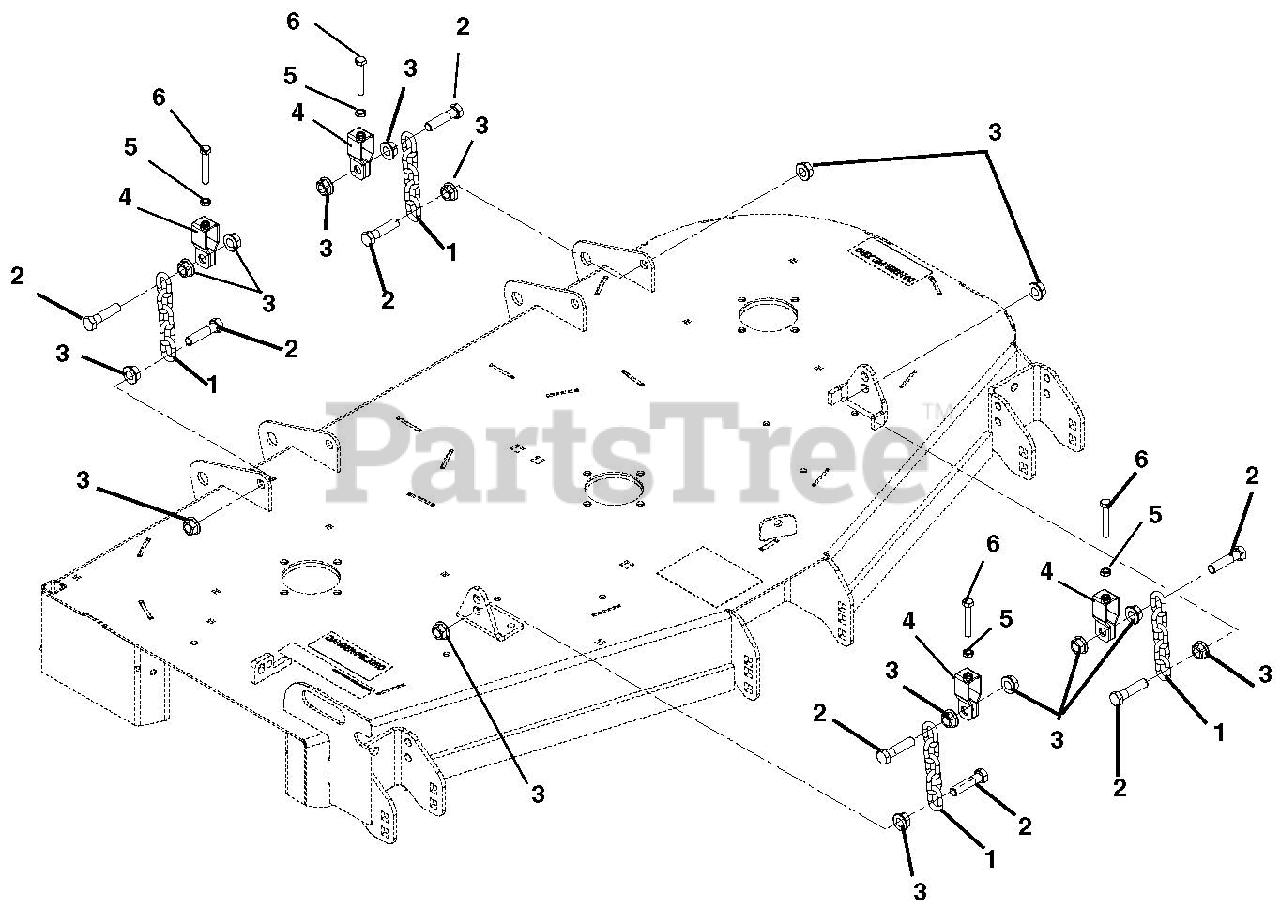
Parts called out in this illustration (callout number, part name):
1	Chain, Link
2	Bolt, Hex M12-1.75 x 50 Class 8.8
3	Nut, Spin Lock-Flange M12-1.75
4	Bracket, Deck Leveling
5	Nut, Jam .312-18
6	Bolt, Hex .312-18 x 2.00 FTH Grade 5
